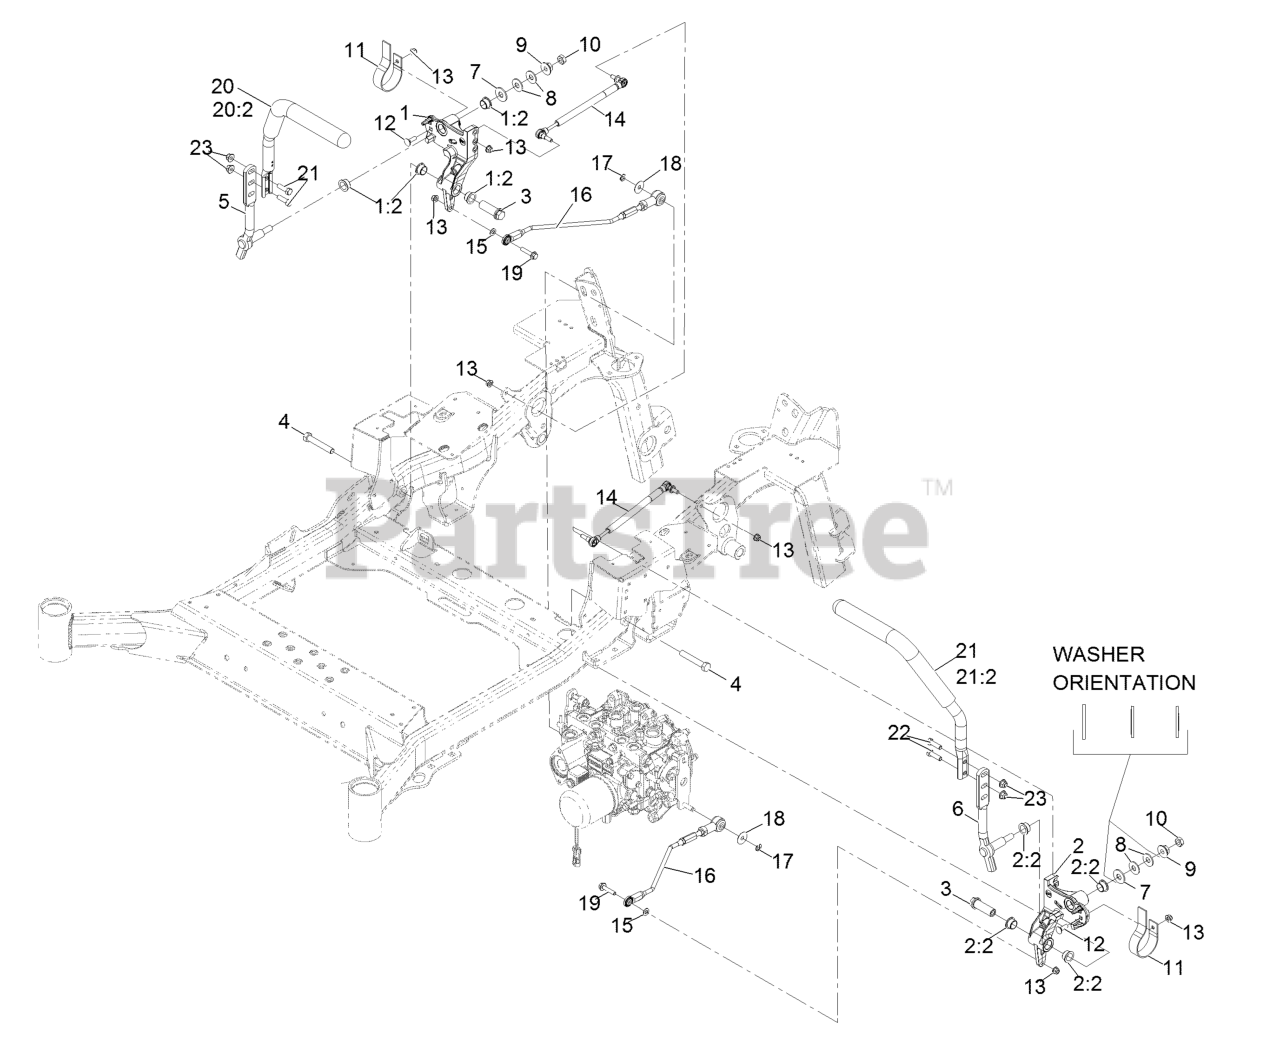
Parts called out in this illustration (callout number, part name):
1	RH Motion Control And Bushing ASM
1:2	Bushing-Flanged
2	LH Motion Control And Bushing ASM
2:2	Bushing-Flanged
3	Hub-Threaded
4	Screw-HH 1/2-13 X 3
5	Lever-Control Motion, RH
6	Lever-Control Motion, LH
7	Washer
8	Washer, Spring Disc 1/2
9	Nut-Hex 1/2-13 Flange
10	Nut-Jam 1/2-13
11	Spring-Leaf
12	Bolt-Carriage 5/16-18 X 1
13	Nut-Nyloc 5/16-18 Flg
14	Damper-Control, Motion
15	Washer-5/16 SAE
16	Front Linkage Rod ASM
17	Ring-Retaining
18	Washer-Plain
19	Screw-Hex Flange 5/16-18 X 1 1/2
20	RH Steering Handle ASM
20:2	Grip-Control, Lever
21	LH Steering Handle ASM
21:2	Grip-Control, Lever
22	Screw-HH 3/8-16 X 1 1/4
23	Nut-Nyloc 3/8-16 Flg
